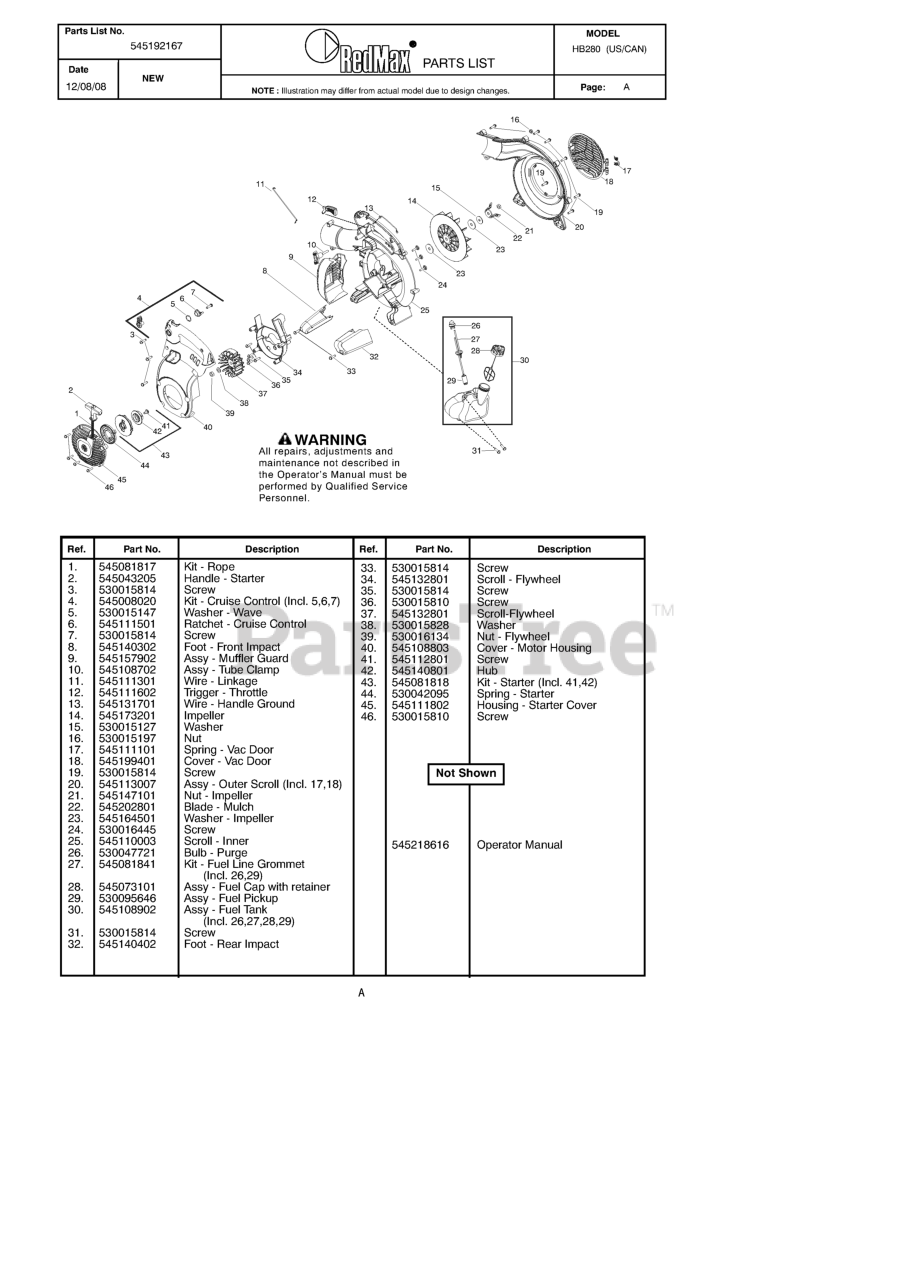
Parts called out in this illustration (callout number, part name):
1	KIT - ROPE
2	HANDLE - STARTER
4	KIT - CRUIS CONTROL (5,6,7)
5	WASHER - WAVE
6	RATCHET - CRUISE CONTROL
8	FOOT - FRONT IMPACT
9	ASSY - MUFFLER GUARD
10	ASSY - TUBE CLAMP
11	WIRE - LINKAGE
12	TRIGGER - THROTTLE
13	WIRE - HANDLE GROUND
14	IMPELLER
17	SPRING - VAC DOOR
18	COVER - VAC DOOR
20	ASSY - OUTER SCROLL (17,18)
21	NUT - IMPELLER
22	BLADE - MULCH
23	WASHER - IMPELLER
25	SCROLL - INNER
26	BULB - PRIMER
27	KIT - FUEL LINE GROMMET;26,29
28	ASSY - FUEL CAP W/RETAINER
29	ASSY - FUEL PICKUP
30	ASSY - FUEL TANK; 26,27,28,29
32	FOOT - REAR IMPACT
34	SCROLL - FLYWHEEL
36	SCREW
37	SCROLL - FLYWHEEL
39	NUT - FLYWHEEL
40	COVER - MOTOR HOUSING
43	KIT - STARTER (41,42)
44	SPRING - STARTER
45	HOUSING - STARTER COVER
46	SCREW
NI	OPERATOR
